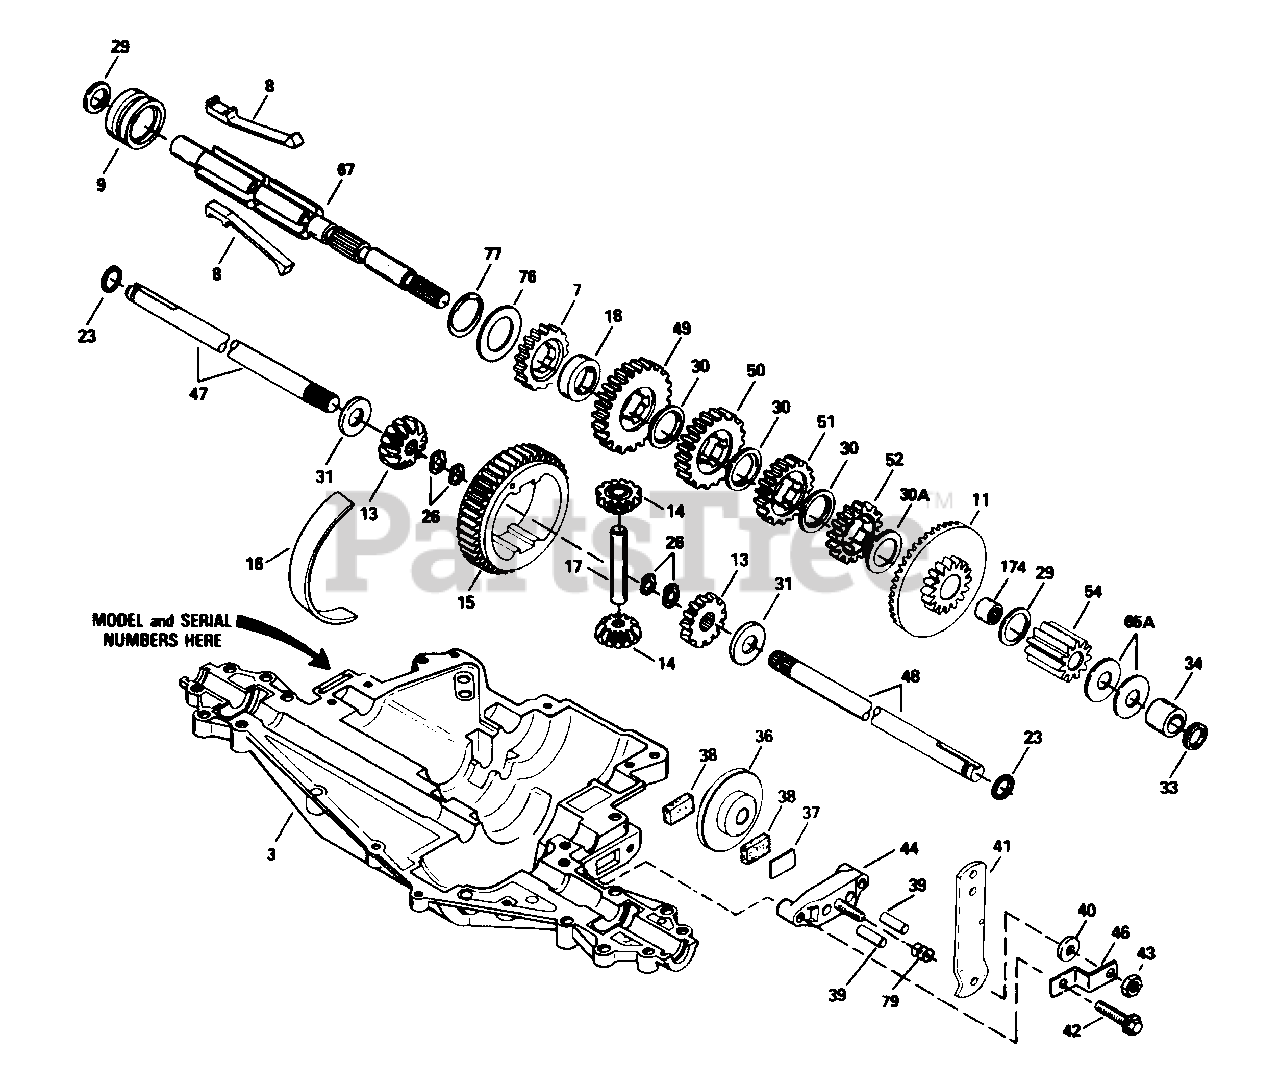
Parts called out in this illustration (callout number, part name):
3	Transaxle Case
7	Spur Gear (22 Teeth)
8	Shift Key
9	Shift Collar
11	Bevel Gear & Bearing (44/16 Teeth)(Incl. Ref. #174)
13	Bevel Gear (16 Teeth)
14	Differential Pinion
15	Ring Gear
16	Bearing Strip
17	Drive Pin
18	Neutral Spacer
23	Seal Ring
26	Retaining Ring (pkg. of 2)
34	Bushing
36	Brake Disk
37	Brake Pad Plate
38	Brake Pad
39	Dowel Pin
41	Brake Lever
43	Locknut
44	Brake Pad Holder
46	Brake Lever Bracket
47	Axle (16-13/16" lg.)
48	Axle (11-5/8" lg.)(Incl. Ref. #26)
49	Spur Gear (35 Teeth)
50	Spur Gear (17 Teeth)
51	Spur Gear (19 Teeth)
52	Spur Gear (20 Teeth)
54	Spur Gear (11 Teeth)
67	Shifter & Brake Shaft
77	Inverted Retaining Ring (pkg. of 2)
174	Needle Bearing
